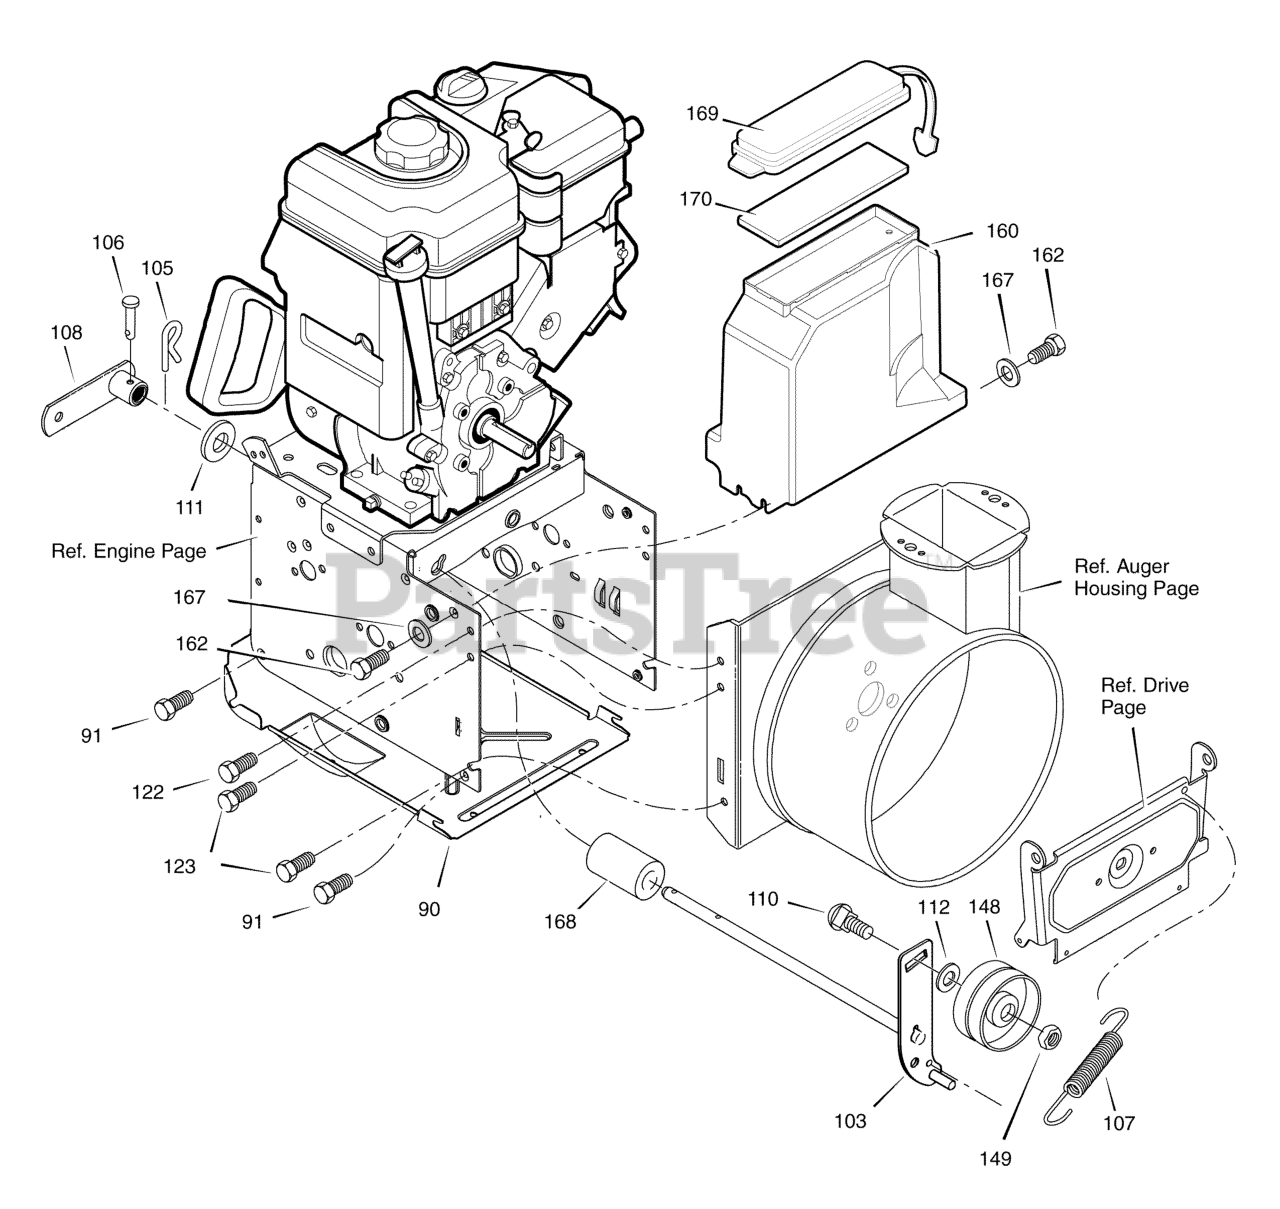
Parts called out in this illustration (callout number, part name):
90	COVER, BOTTOM
91	SCREW, 1/4-20 X .63
103	IDLER ASSEMBLY, AUGER
105	PIN, HAIR .38DIA X 1.64LG
106	PIN, CLEVIS 3/16" DIA
107	SPRING, TENSION
108	SPRING ATTACH ASSEMBLY
110	BOLT, 3/8-16 X 1.25 CARRIAGE
111	WASHER, FLAT
122	SCREW, TAP 5/16-18 X .50
123	SCREW, TAP 5/16-18 X .75
148	PULLEY, IDLER
149	NUT, JAM 3/8-16
160	COVER, BELT
162	SCREW, TAP
167	WASHER, FLAT
168	SPACER, AUGER BRACKET
169	LID, TOOLBOX
170	FOAM PAD
